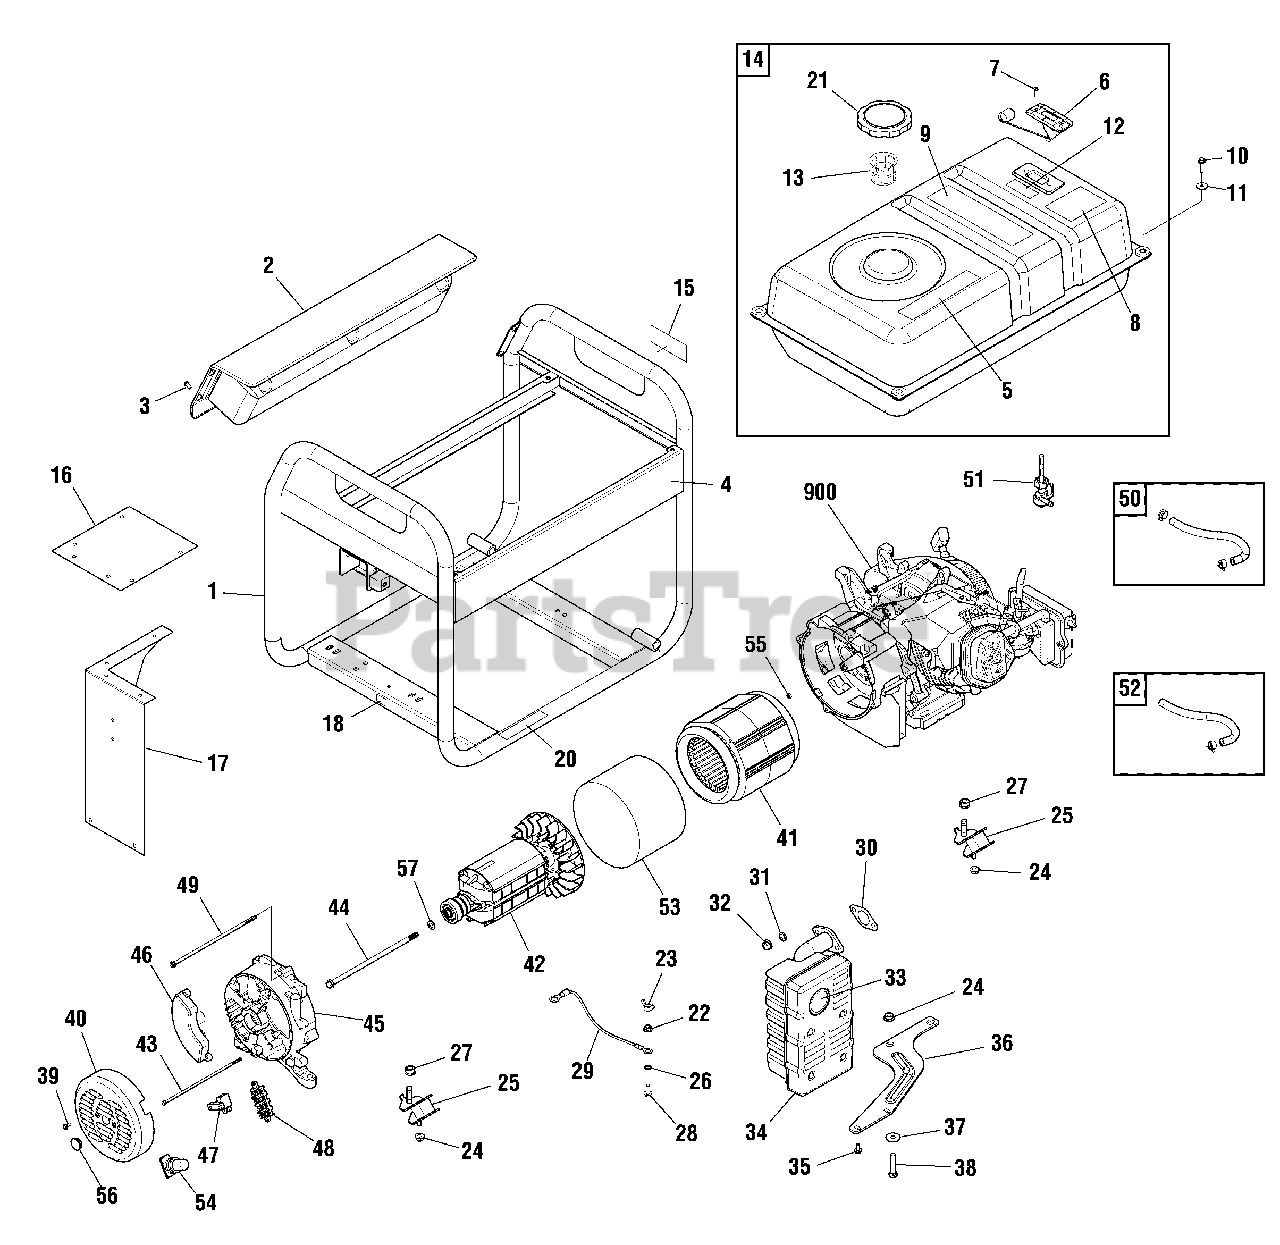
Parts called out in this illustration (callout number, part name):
2	PANEL-CONTROL
22	* NUT, Flange Lock, M6
24	* NUT, Flange Lock, M8
25	MOUNT-VIBRATION
26	* WASHER, Shakeproof, Ext, M6
27	* NUT, Flange Lock, M10
28	* SCREW, Flange, M6 x 16
30	GASKET
31	* WASHER, Lock, M8
32	* NUT, Hex, M8 1.25
35	* SCREW, Flange, M6 x 12
36	BRACKET-MUFFLER
37	* WASHER, Flat, M8
38	HHCS-M8-1.25 x 40
45	CARRIER-BEARING
46	VOLTAGE REGULATOR
50	KIT-FUEL HOSE
52	HOSE-VAPOR
900	** ENGINE
